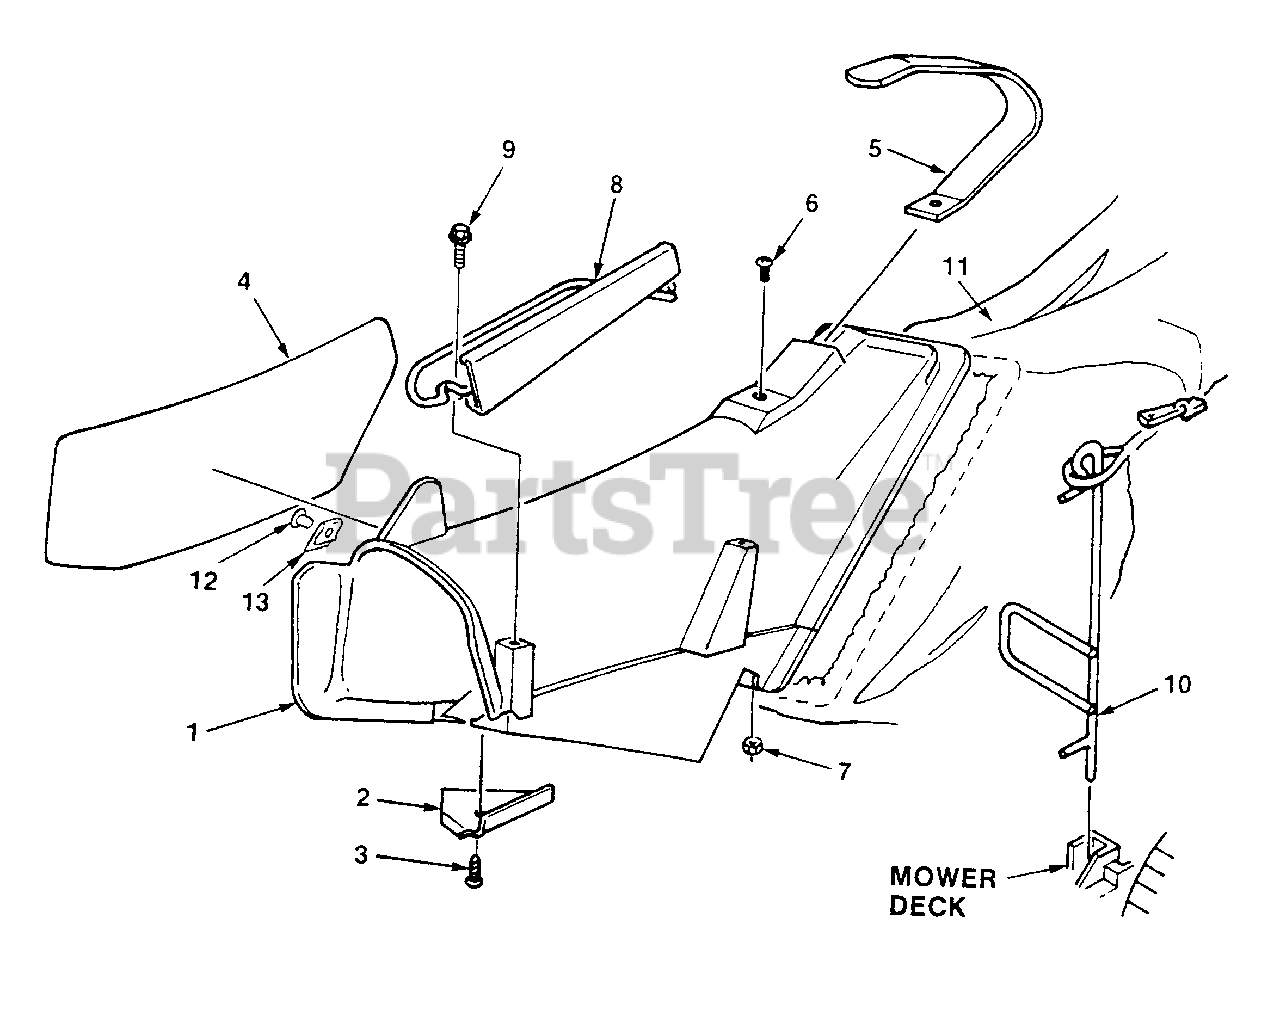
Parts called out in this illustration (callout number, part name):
1	ADAPTER & Scoop
2	PLATE- Cover
3	SCREW- Rd. Hd.
4	DECAL- Instruction
5	HANDLE- Adapter
6	SCREW- Truss Hd.
8	RAIL AND GUIDE
9	SCREW- Hex hd.
10	BAG- Support
11	GRASS BAG Standard
12	RIVET- Blind
13	CLIP- Wear
